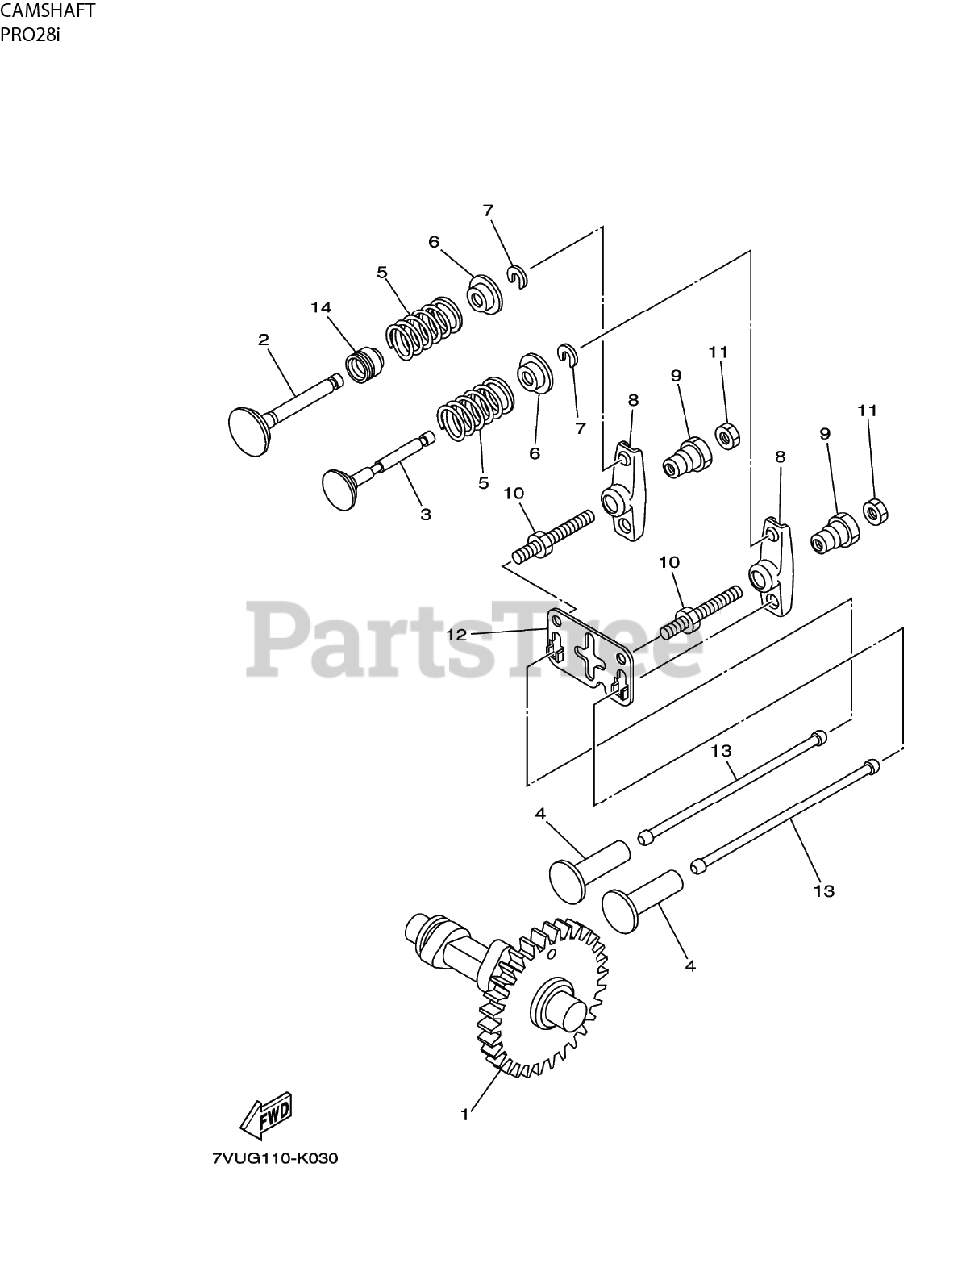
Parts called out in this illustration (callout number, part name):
1	CAMSHAFT ASSEMBLY
2	VALVE, INTAKE
3	VALVE, EXHAUST
4	TAPPET, VALVE - LIFTER VALVE
5	SPRING, COMPRESSION
7	LOCK, VALVE SPRING RETAINER
8	ARM, VALVE ROCKER
9	PIVOT, ROCKER ARM
10	STUD, BOLDT
11	NUT, LOCK
12	PLATE, GUIDE PUSH ROD
13	ROD, VALVE PUSH
14	SEAL, VALVE STEM
